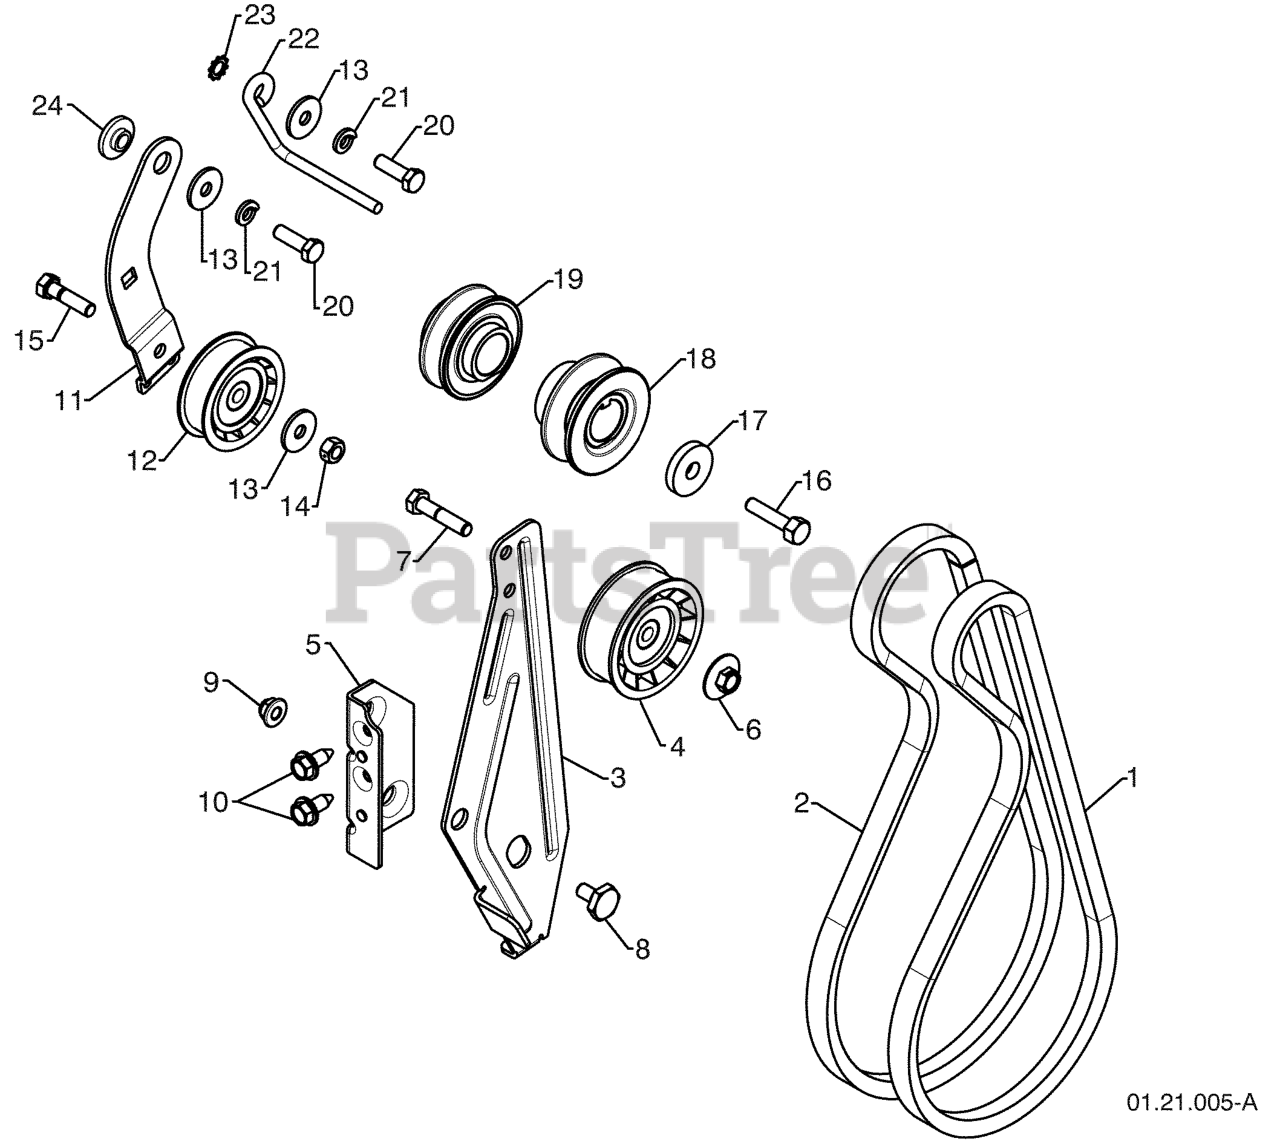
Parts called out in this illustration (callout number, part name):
1	V-BELT.IMPELLER
2	TRACTION BELT
3	ARM.IDLER.BRAKE.
4	PULLEY.W/SPACER.2.75
5	RP BRACKET.IDLER.PIVOT
6	NUT.FLANGE.HEX.5/16X18.BLACK
7	HEX BOLT
8	BOLT.SHOULDER.1/2X12
9	NUTNYLOK.FLRANGE.5/16-18
10	BOLT.HEX.HD.WASHER.5/16-18X.75
11	RP ARM.ASM.TRACTION.IDLER
12	PULLEY.W/SPACER.2.25
13	STEEL WASHER
14	NUT.CENTERLOCK.5/16-
15	BOLT.5/16-18X1-1/4 FULL.THREAD
16	SCREW, HEX HD 3/8-24 X 1-3/8
17	WASHER.400X1.25X5.
18	PULLEY ENG IMPELLER
19	PULLEY.ASM.ENG.TRACTION.1.00
21	WASHER.LOCK.HVY.HLCL.SPR.5/16
22	BELT.GUIDE.RH
23	WASHER EXT TOOTH LOCK 5/16
24	RP BUSHING, IDLER PIVOT
